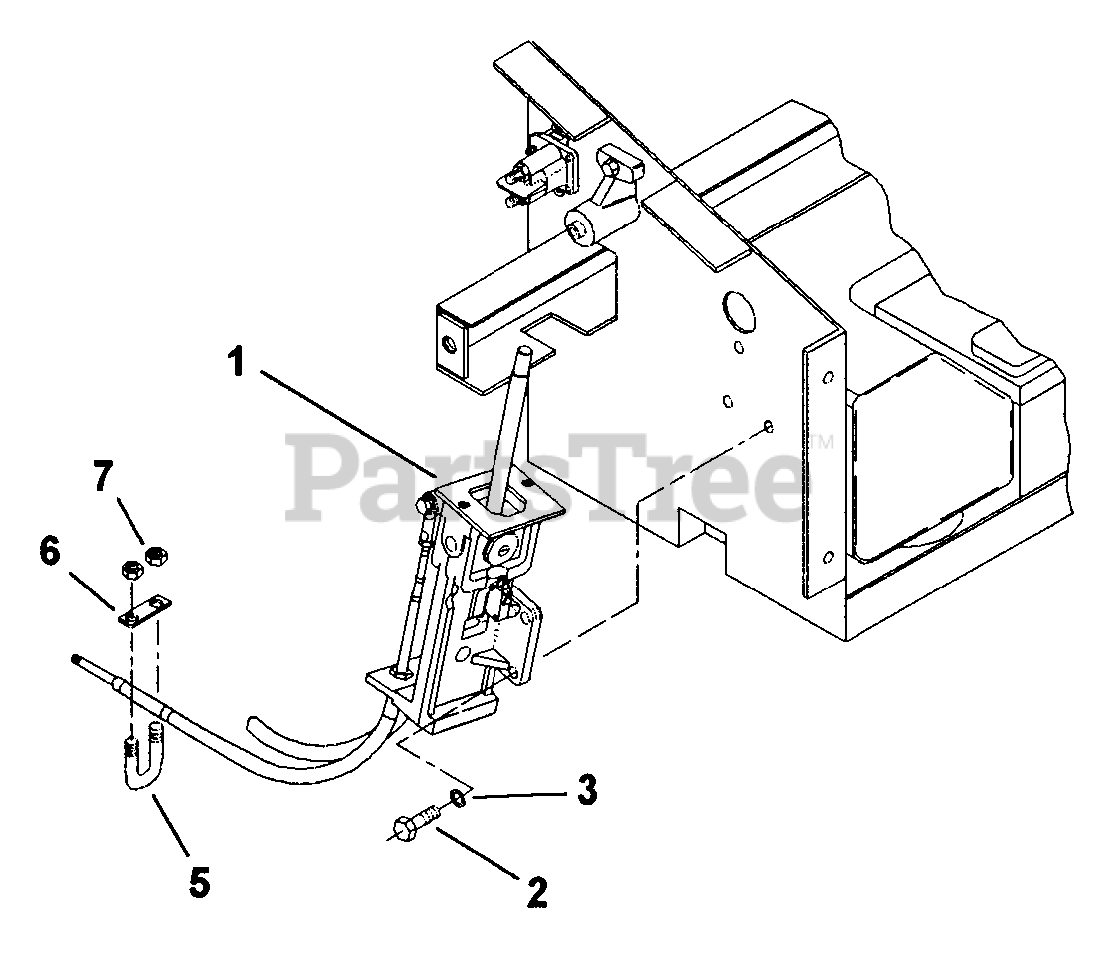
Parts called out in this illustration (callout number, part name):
1	JOYSTICK YOKE ASSEMBLY
2	CAP SCREW, 1/4-20 x 3/4", Gr.5
3	LOCK WASHER, 1/4" Split Ring
5	U-BOLT, 5/16-18 X 1 3/16"
6	U-BOLT SPACER
7	NUT, 5/16-18, Nylock
